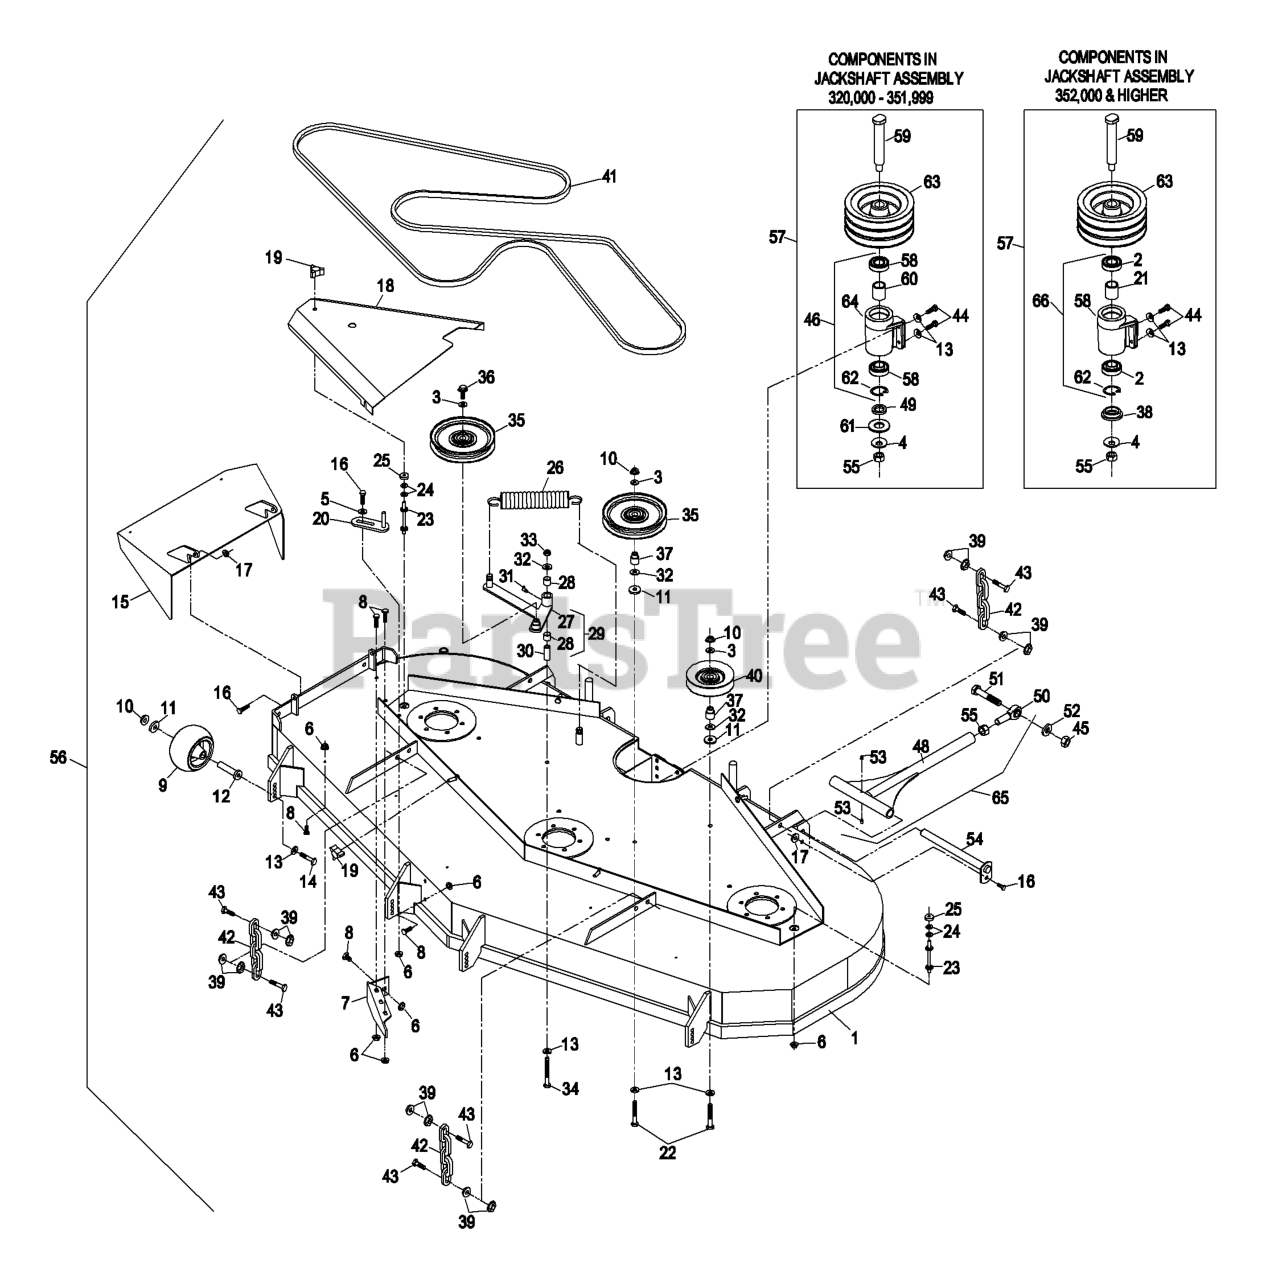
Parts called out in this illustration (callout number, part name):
2	BEARING-JACKSHAFT
3	WASHER-FLAT
4	WASHER-SPRING
5	WASHER-SPRING
7	WLD,BAFFLE DISCHARGE
8	SCREW-HH
9	ROLLER-SCALP, ANTI
10	NUT-HHF, WHIZ
12	BUSHING-ROLLER
13	WASHER-BELLEVILLE
14	SCREW-HH
15	WLD,CHUTE 72
16	SCREW-HH
17	NUT-LOCK, NI
18	SHIELD,BELT RH
19	KNOB-3 PRONG
20	GUIDE-BELT
21	SPACER-BEARING
22	SCREW-HH
23	STUD-SHIELD, BELT (SHORT)
24	WASHER-FLAT
28	SLEEVE-BEARING
30	BUSHING
31	FITTING-GREASE, 90 DEG
32	WASHER-FLAT
33	NUT-LOCK, NI
34	SCREW-HH
36	SCREW-HHF
37	BUSHING-IDLER
38	SPACER-GUARD, BOTTOM
40	PULLEY-IDLER
41	BELT-V
42	CHAIN-LIFT, DECK
43	SCREW-HH
44	SCREW-HH
45	NUT-HEX
46	Asm, Jackshaft Housing W/Brgs
47	SPINDLE HSG ASSYCOMP72
49	SPACER-PULLEY/BEARING
50	BALLJOINT-SPHERICAL
51	SCREW-HH
52	WASHER-LOCK
53	FITTING-GREASE
54	PIN-STRUT
55	NUT-HEX
56	Complete Deck Assy
57	ASM,JACKSHAFT
58	BEARING
59	JACKSHAFT,LAZER XP
60	SPACER-BEARING
61	GUARD-BEARING, BOTTOM
62	RING-SNAP
65	STRUT WLDMT S/A
